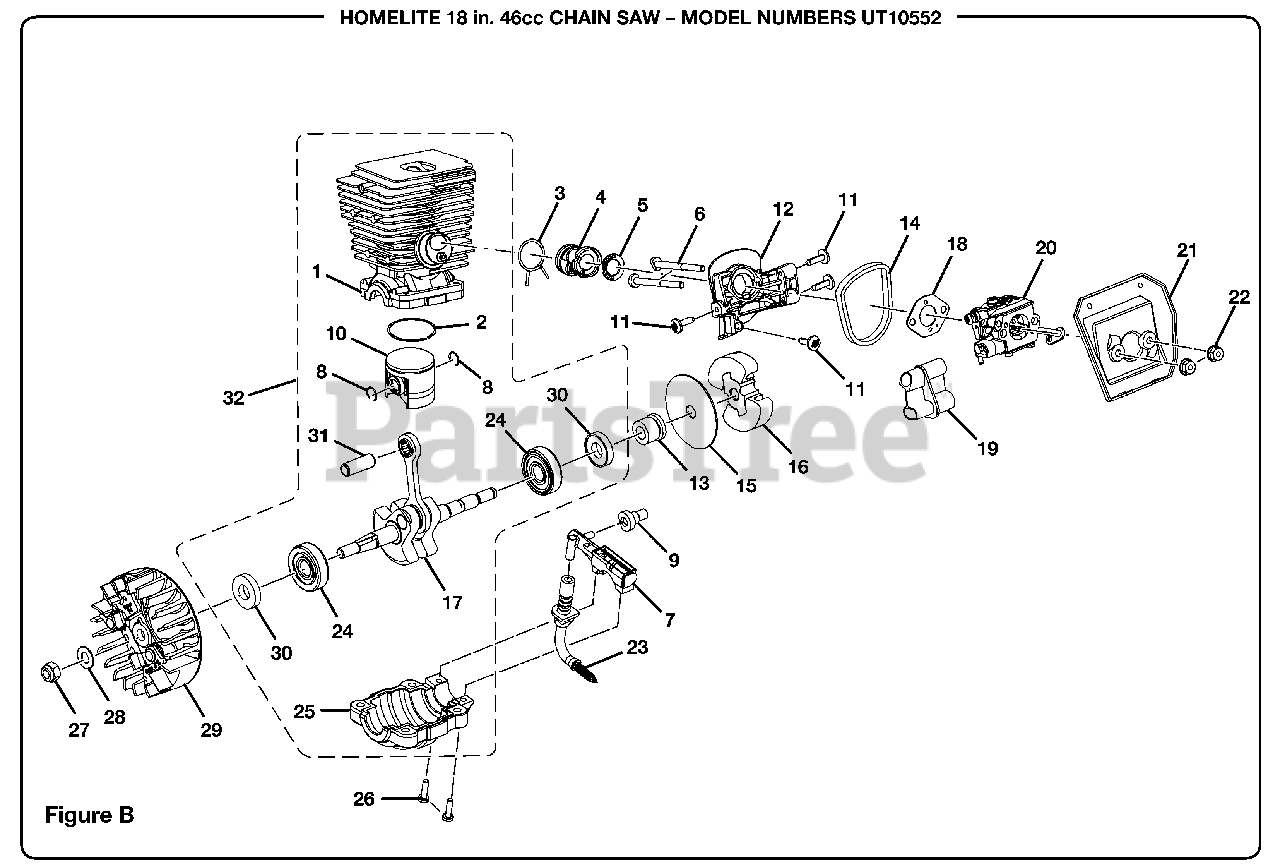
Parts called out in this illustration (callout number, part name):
2	Piston Ring
3	Wire Clamp
4	Intake Boot Rubber
5	Carburetor Plate
6	Screw (10-24 x 2-1/4 in.)
7	Oil Pump Assembly
8	Retaining Ring
9	Oil Outlet Grommet
10	Piston (46cc)
11	Screw (10-14 x 5/8 in. Torx Pan Hd.)
12	Carburetor Spacer
13	Left Hand Worm
14	Spacer Seal
15	Thrust Washer
16	Clutch Assembly
17	Crankshaft Assembly
18	Carburetor Gasket
19	Carburetor Grommet
20	Carburetor Assembly
21	Air Filter Plate
22	Flange Nut (10-24)
23	Oil Intake Tube with Spring
24	Bearing Case with Bearing
25	Crankcase
26	Screw (8-32 X 5/8 in. Pan Hd.)
27	Nut (5/16-24)
28	Flat Washer
29	Rotor Assembly
30	Shaft Seal
31	Piston Pin
32	Short Block Assembly
